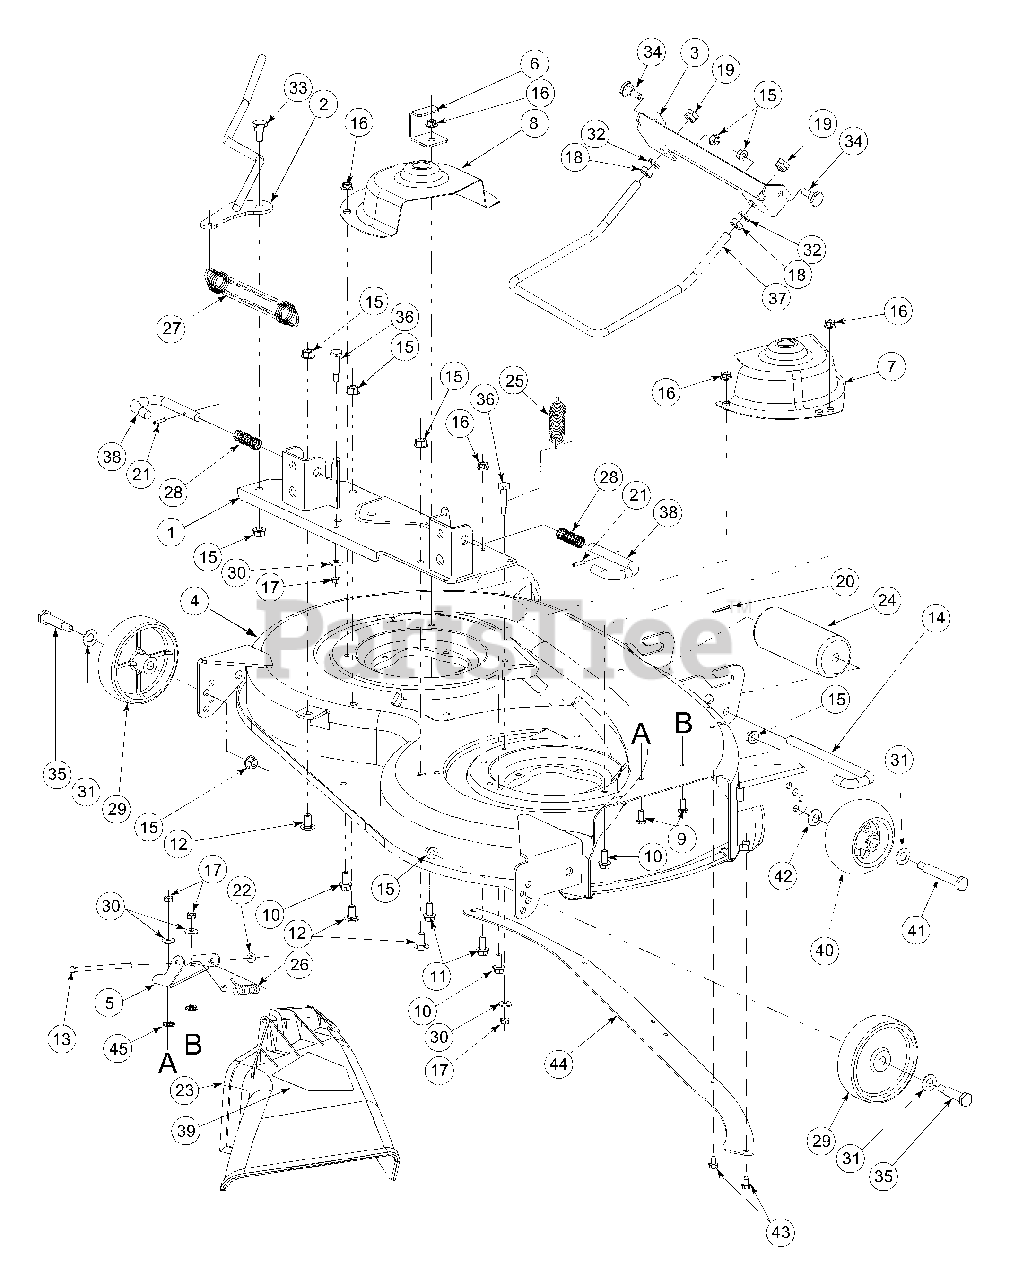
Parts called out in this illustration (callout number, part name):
4	Graphic, Tension Lever
4	Graphic, Safety Top/LH Deck
4	Graphic, Cut
4	Graphic, 38" Cut
5	Bracket, Hinge Mounting
9	Screw, Hex Cap, 1/4-20 x .62 GR5
10	Screw, Hx Wsh Hd Tapp, 5/16-18 x .75
11	Screw, Hex Cap, 5/16-18 x .75 GR5
12	Bolt, Carriage, 3/8-16 x .75
13	Pin, Hinge, .25 Dia x 6.75 Lg
14	Pin, Roller, 1/2 Dia x 7.31 Lg
15	Nut, Hex Flange Lock, 3/8-16
16	Nut, Hex Flange Lock, 5/16-18 GR5
17	Nut, Hex, 1/4-20
18	Nut, Hex Jam, 1/2-13 GR5
19	Nut, Hex Insert Lock, 1/2-13
20	Pin, Cotter, 3/32 x 1.25
21	Pin, Spirol Spring, 3/16 x .75
22	Cap, Speed Nut
23	Deflector Assy,
25	Spring, Extension, .88 OD x 6.12
26	Spring, Torsion
27	Spring, Extension, 1.25 OD x 8.15
28	Spring, Compression
29	Wheel, Deck, 5 in. Dia
30	Washer, Bell, .265 x .75 x .062
31	Washer, Flat, .510 x 1.0 x .060
32	Washer, Lock, 1/2
33	Bolt, Shoulder, .498 Dia x .340 Lg
34	Bolt, Shoulder, .50 Dia x .434 Lg
35	Bolt, Shoulder, .498 Dia x 1.64 Lg
36	Bolt, Shoulder, .375 Dia x 1.16 Lg
37	Rod, Front Lift
38	Pin, Mower Support
39	Graphic, Danger
40	Wheel, Deck w/Fitting
40	Lube Fitting
41	Bolt, Shoulder, 1/2 x 2.5
42	Washer, Bell, .401 x .870 x .063
43	Screw, Self Tapping, 1/4-20 x .5
45	Nut, Push, 1/4
